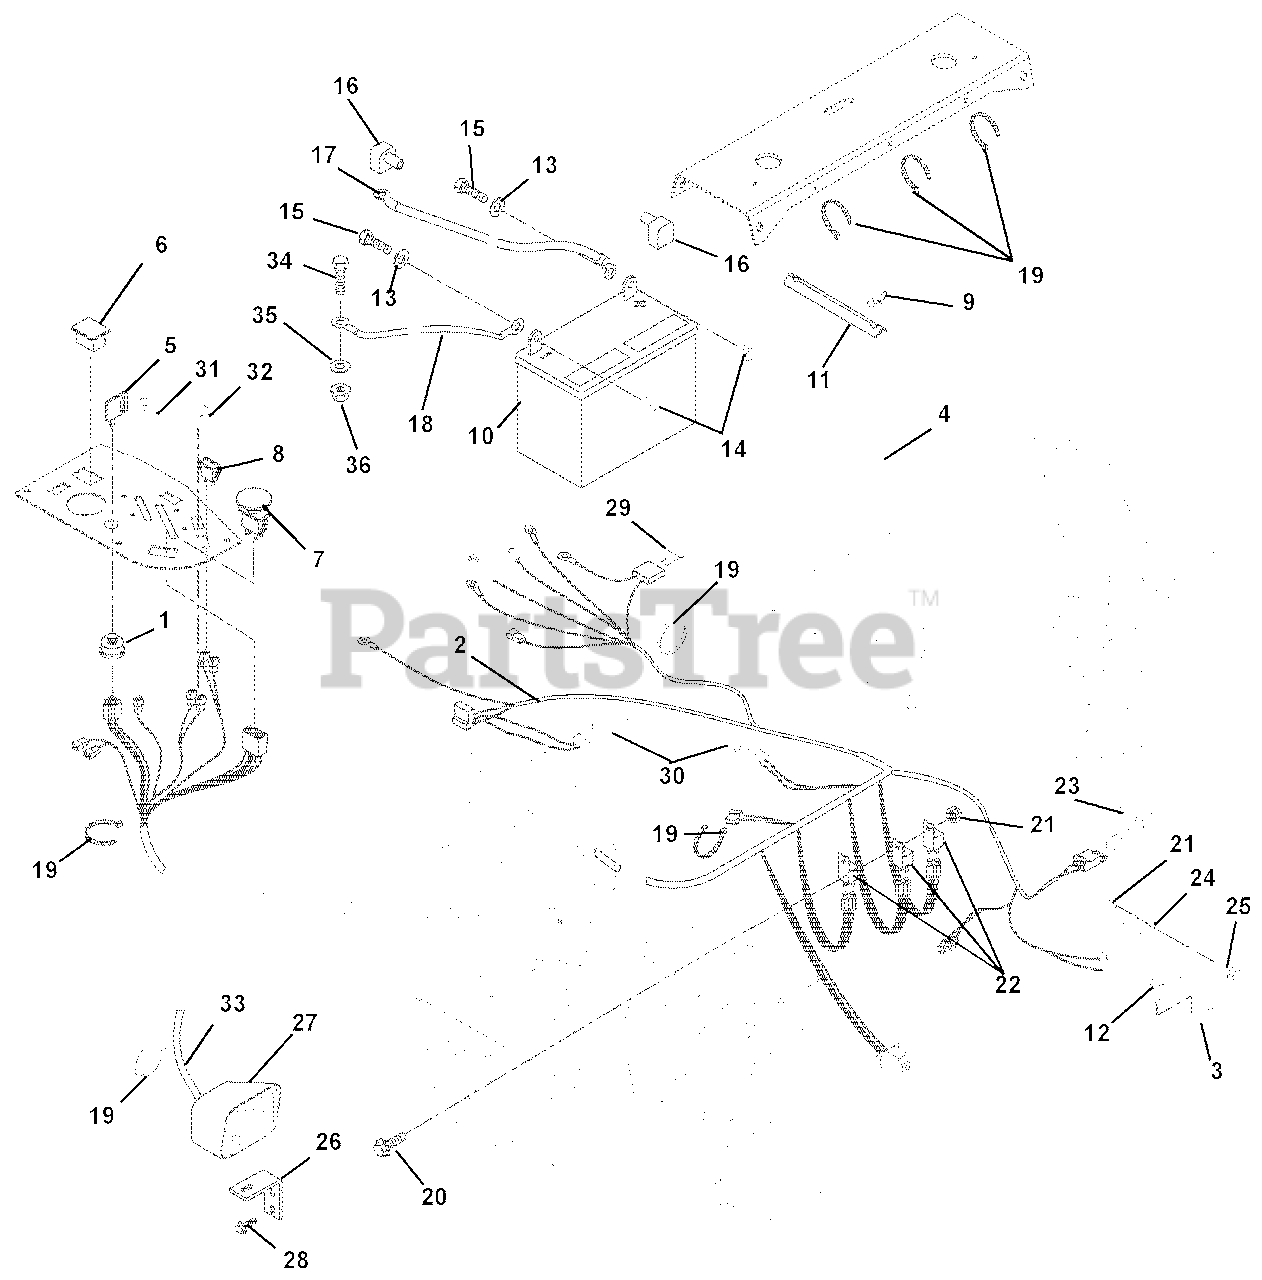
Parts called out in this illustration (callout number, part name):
1	Switch, Ignition
2	Harness, Z-6 Pin Wiring (EYE-Q) (045, 046, 047, 049, 052, 053)
3	Mount, Safety Switch
4	Rod, Battery Holddown .25 x 6.62
5	Key, with Shield
6	Hour Meter
7	Switch, PTO Clutch
8	Light-Indicator Kit (045, 046, 047, 049, 052, 053)
9	Nut-Locking Wing .25-20
11	Hold Down
12	Screw-Tapping .25-20 x .50 Hex Washer Head
13	Washer-Flat-Steel .281 x .620 x .065
14	Nut-Locking-Top-Flange .25-20
15	Bolt-Hex .25-20 x .75 Grade 5
16	Battery Terminal Boot, Red
17	Starter Cable 13 in.
18	Ground Cable
19	Cable Tie
20	Screw-Machine 10-24 x .50 Hex Washer Head
21	Nut-Locking-Nylon 10-24 With Insert
22	Relay (Included with Harness)
23	Switch- Snap Mounting
24	Switch-Single Pole
25	Screw-Machine 10-24 x .75 Hex Washer Head
26	Bracket, Headlight Mounting Left
27	Headlight
28	Screw-Tapping .38-16 x .50 Hex Washer Head
29	Fuse, 30 Amp (Included with Harness)
30	Diode, Connector Shell
31	Key Chain
32	Switch, Light
33	Harness, Headlight Kit
34	Bolt-Hex .31-18 x .75 Grade 5
35	Washer-Flat-Steel .344 x .688 x .065
36	Nut-Locking-Top-Flange .31-18
